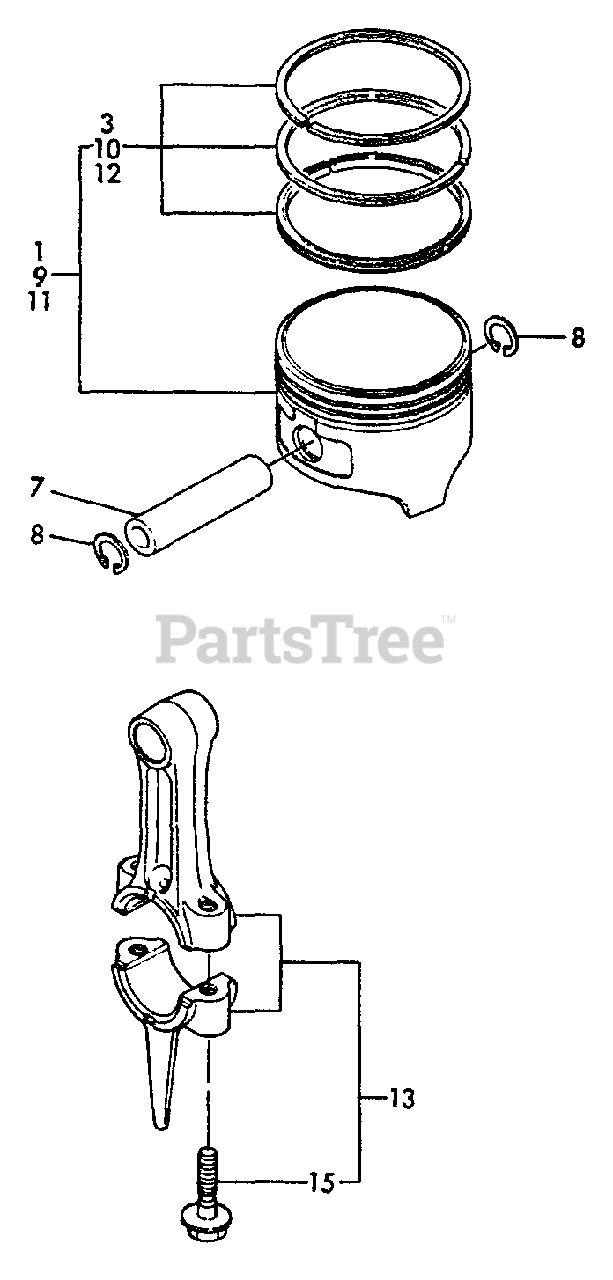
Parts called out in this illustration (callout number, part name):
1	PISTON KIT
3	RING, PISTON
7	PIN, PISTON
8	RING, RETAINING - 13
9	PISTON KIT
10	RING, PISTON
11	PISTON KIT
12	RING, PISTON
13	CONNECTING ROD ASSY
15	BOLT
